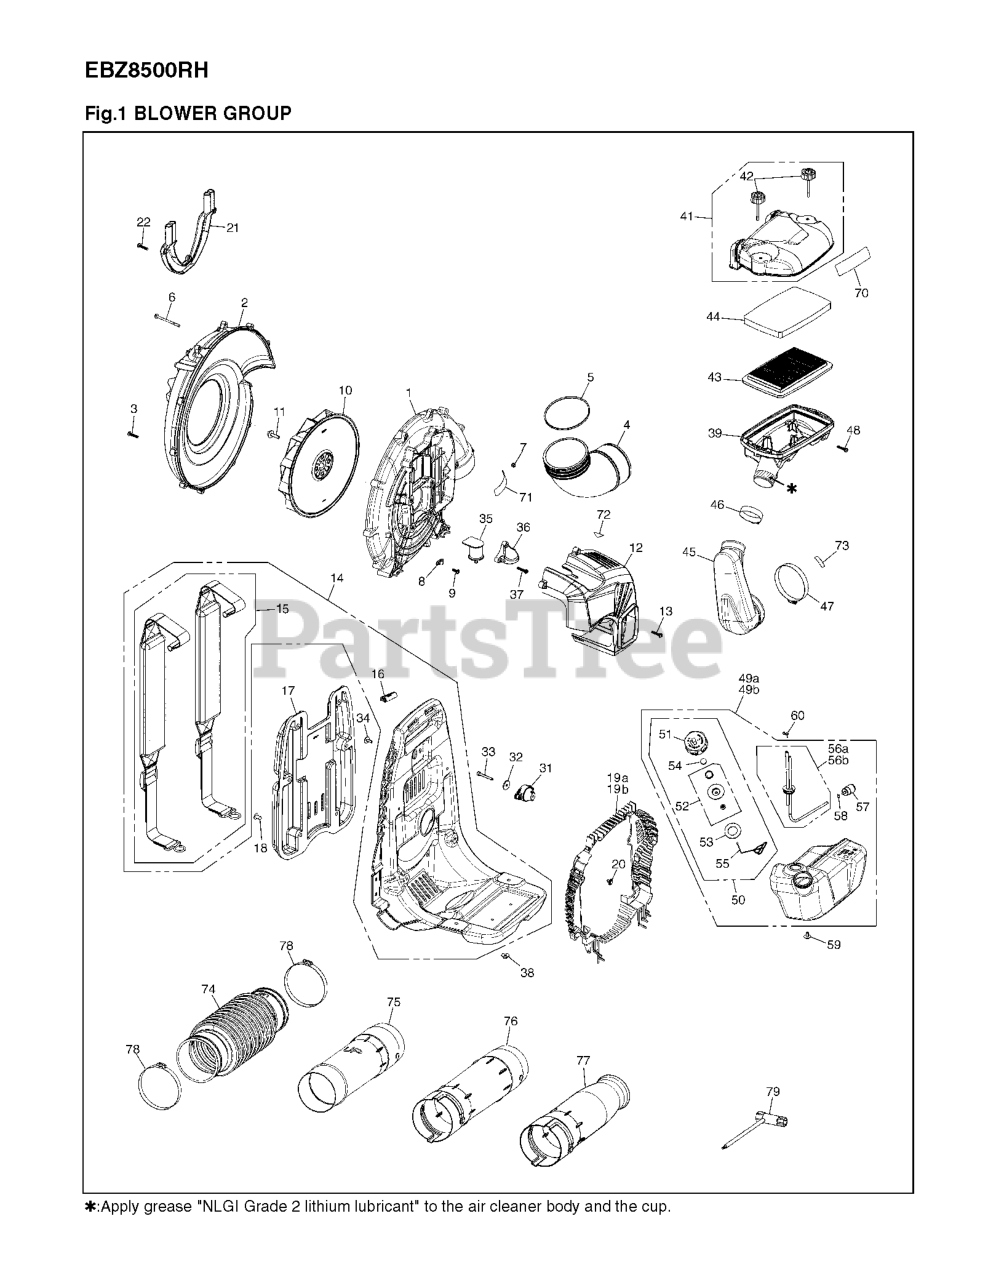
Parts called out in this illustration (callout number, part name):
1	CASE VOLUTE
2	VOLUTE,COVER
5	0-RING
8	CLAMP
10	FAN
12	ENGINE COVER
14	FRAME ASSY
15	BAND ASSY (RPLS 848L583611)
16	CLIP
18	CLIP
20	CLIP
31	DAMPER UPPER
32	WASHER
33	BOLT
39	BODY AIR FILTER
41	COVER ASSY
42	KNOB BOLT
43	ELEMENT
44	ELEMENT
45	HOSE
46	CLAMP(F64)
47	CLAMP(F96)
50	ASSY FUEL CAP
52	HOLDER-A
57	FILTER ASSY
58	CLIP
60	CLIP
70	DECAL, CLEANER
73	LABEL,CHOKE
74	HOSE
77	PIPE,END
78	CLAMP(F115)
79	SOCKET
